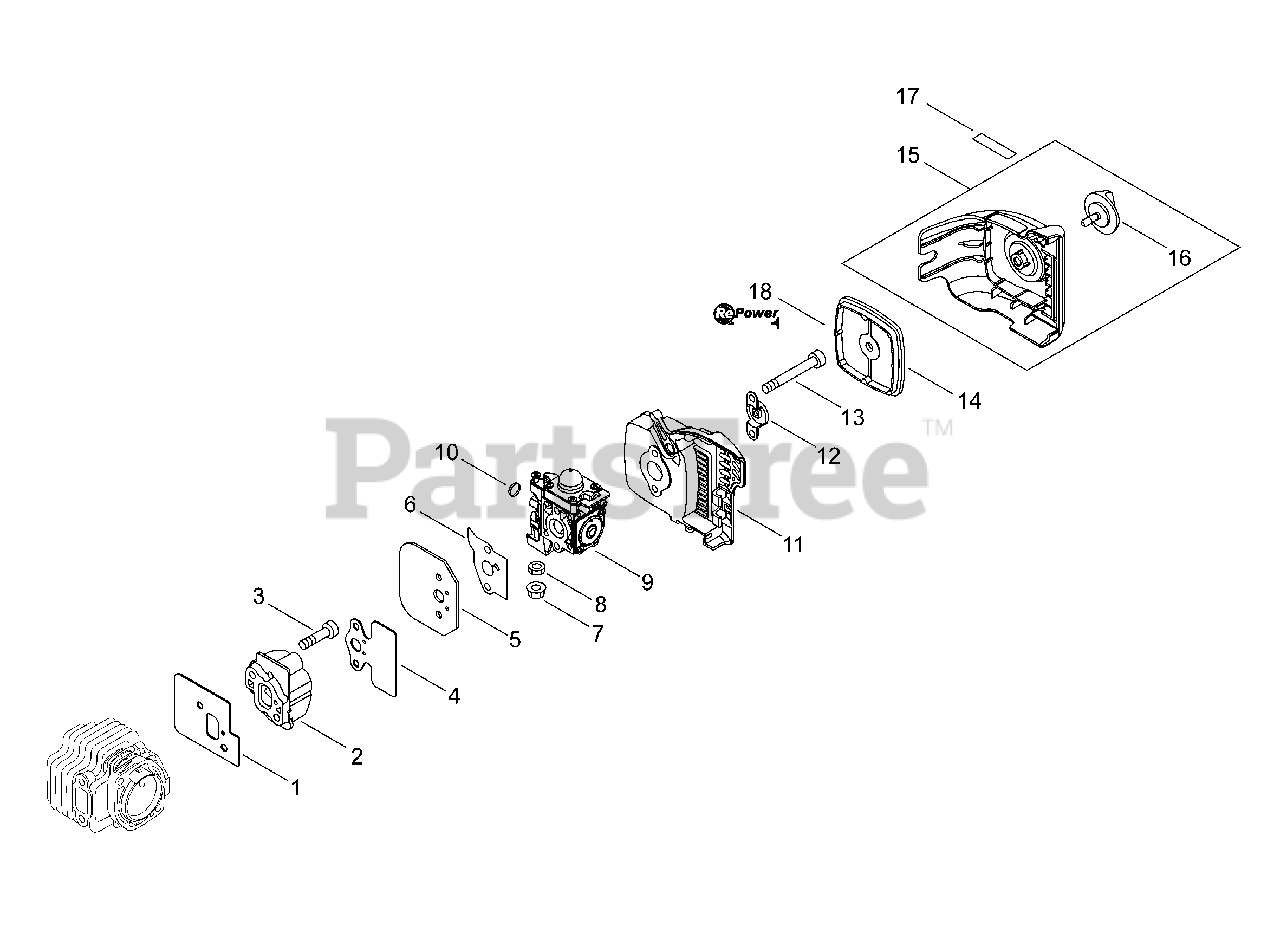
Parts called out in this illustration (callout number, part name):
1	GASKET, INTAKE
2	INSULATOR, INTAKE
3	BOLT, TORX 5×25
4	GASKET, INTAKE
5	PLATE, INSULATOR
6	GASKET, INTAKE
7	NUT, FLANGE M6
9	CARBURETOR RB-K119
11	CASE, AIR FILTER
12	PLATE, PREVENT
13	BOLT, TORX 5×65
14	FILTER, AIR - DOUBLE LAYER
15	COVER SET, AIR FILTER
16	THUMBSCREW
17	LABEL, CHOKE
18	FILTER KIT - REPOWER
